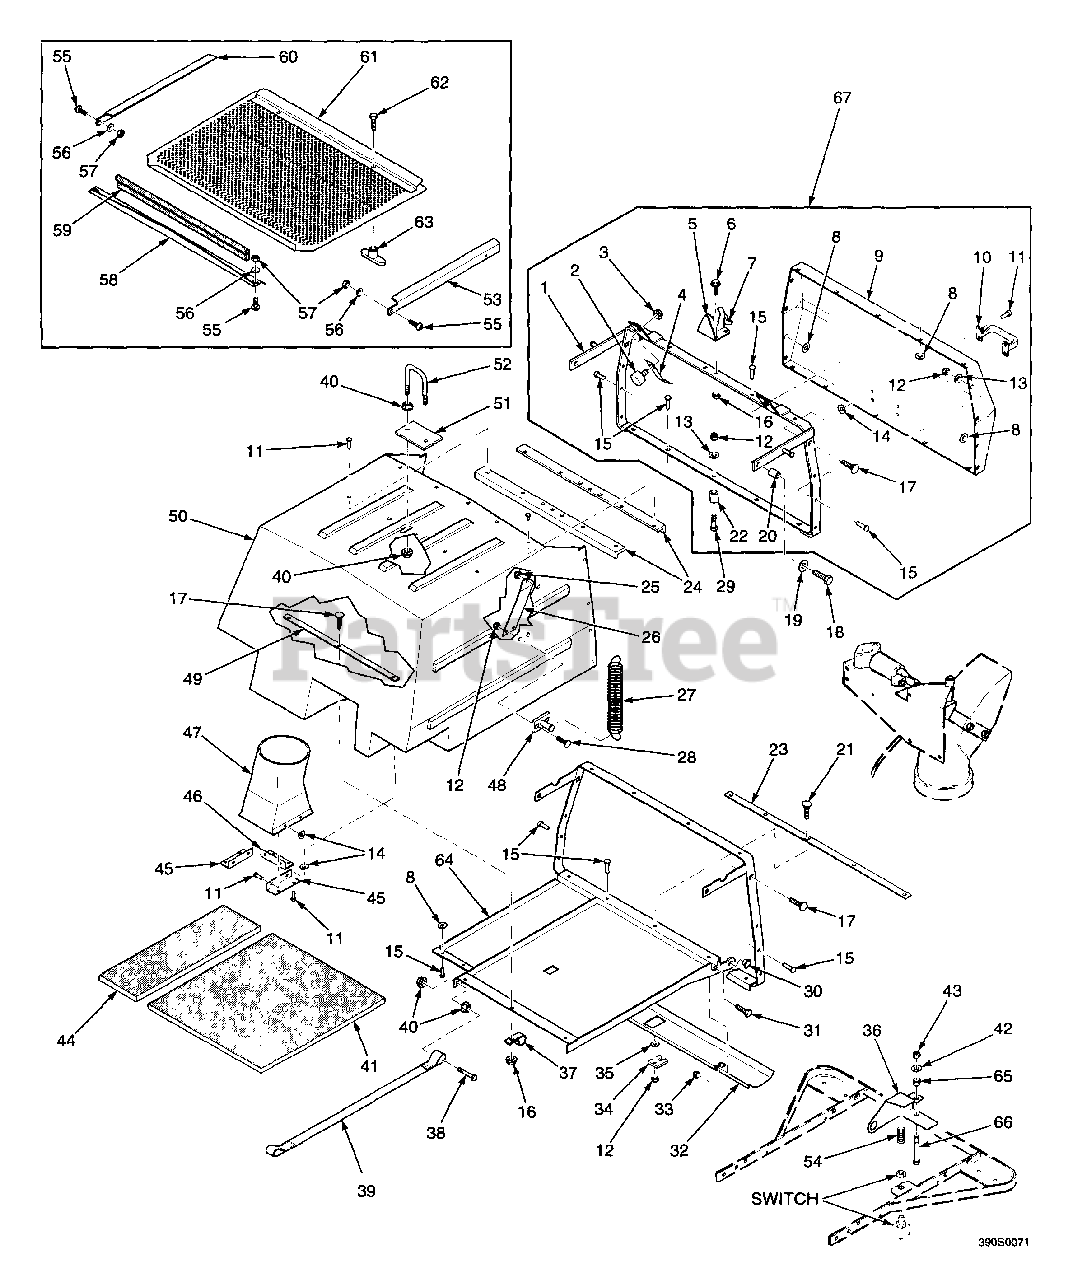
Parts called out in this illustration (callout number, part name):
1	Frame, Hopper Door
2	Bumper, Rubber
3	Serr. Fl. Hex Nut, 5/16-18
4	Retainer, Screen
5	Guard, Latch
6	Serr. Fl. Hex Head CPSCR, 1/4-20 x 1.00"
7	Latch, Hopper Door
8	Flatwasher, 1/4 (.258 x .500 x .0598)
9	Door, Hopper
10	Handle
11	Pop Rivet, 3/16 x .652"
12	Hex Locknut, Elastic Stop, 1/4-20
13	Flatwasher, 1/4 (.312 x .75 x .065)
14	Flatwasher, 3/16 (.196 x .469 x .048)
15	Rivet, Lok Bolt, 1/4 x 85"
16	Serr. Fl. Hex Nut, 1/4-20
17	Carriage Bolt, 1/4-20 x 1.00
18	Bolt, Hex Head, 3/8-16 x 1-1/2
19	Flatwasher, 3/8 (.391 x .938 x .105)
20	Sleeve
21	Carriage Bolt, 1/4-20 x 1-1/4"
22	Boss, Centering
23	Support, Door - Inside
24	Support, Hopper - Top
25	Hex Locknut, Elastic Stop, 3/8-16
26	Support, Hinge (L.H Shown)
27	Spring, Hopper Door
28	Carriage Bolt, 1/4-20 x 3/4"
29	Bolt, Hex Head, 1/4-20 x 1 25"
30	Bushing
31	Bolt, Hex Head, 5/16-18 x 3/4"
32	Shield, Hopper
33	Hex Locknut, Elastic Stop, 5/16-18
34	Tab, Centering
35	Spacer
36	Lever, Hopper Switch
37	Clamp, Cable - .50"
38	Bolt, Hex Head, 3/8-16 x 2-1/4"
39	Strap, Hopper Stop
40	Serr. Fl. Hex Nut, 3/8-16
41	Insulation, Hopper - Rear
42	Flatwasher, 5/16 (.375 x .875 x .083)
43	Locknut, 5/16-18 Elastic Stop
44	Insulation, Hopper - R.H.
45	Mount, Transition Chute - Side
46	Mount, Transition Chute - Rear
47	Chute, Transition
48	Anchor, Spring
49	Bar, Clamp
50	Hopper
51	Plate
52	U-Bolt, 3/8-16
53	Guide, Screen - Upper L.H.
54	Spring, Switch
55	Screw, Round Head, #10-32 x 1/2"
56	Lockwasher, External Tooth, #10
57	Hex Nut, #10
58	Screen Stop
59	Trim Seal
60	Guide, Screen - Upper R.H.
61	Screen
62	Bolt, Hex Head 5/16-18 x 3/4"
63	Wingnut, Plastic
64	Frame, Hopper
65	Spring, Switch Lever
66	Hex Head Bolt, 5/16-18 x 4.0"
67	Door Assy, Hopper
